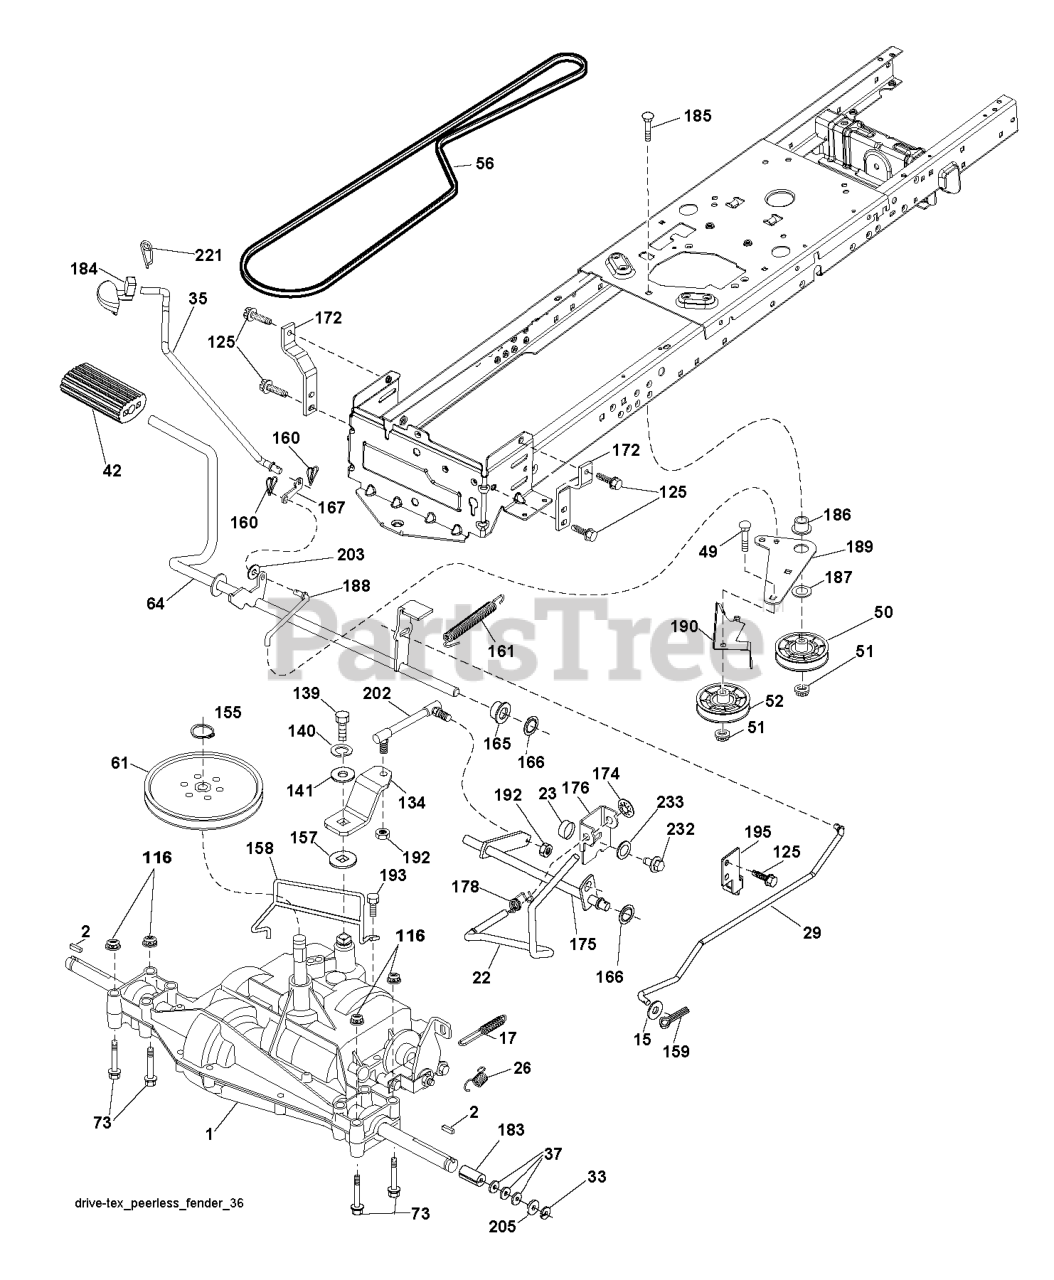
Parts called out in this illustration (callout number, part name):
2	SQUARE KEY
15	WASHER
17	SPRING.BRAKE.PEERLESS.TEX
22	ROD.SHIFT.FENDER.TLT.2006
23	KNOB.DUCKHEAD.1/2
26	SPRING.BRAKE.RTN.GR.DR
29	ROD.BRAKE.PEERLESS
35	ROD.CNTRL.PARK.PREDATOR.LT.TEX
42	PEDAL COVER T
50	IDLER.FLAT.910.OFFSET
51	NUT LOCK FLG 3/8-16 UNC
52	IDLER.V-GROOVE.910.OFFSET
56	V-BELT.TRACTOR.DRIVE.P
61	PULLEY TRANS
64	SHAFT.ASM.PEDAL.BRAKE.
73	BOLT HEX 5/16-18 GR 5
116	NUT LOCK HEX FLANGE 5/16-18
125	SCREW
139	BOLT 1/4-28X3/4
140	LOCKWASHER
141	WASHER LT
155	RETAINING RING LT
157	WASH-SHFT PLT LT
158	KEEPER.PMS.18/20.D4365
159	COTTER PIN
160	RETAINER CLIP
161	SPRING, RETURN LT
165	BUSHING.SHAFT.BRAKE.HAND
166	NUT.PUSH.625
167	LATCH.BRAKE.SPRING
172	STRAP.TRQ.LH.GEAR.DRIV
174	NUT.PUSH.500.2006
175	SHAFT ASM SHIFT
176	ARM.CLEVIS.ROD.SHIFT
178	SPRING.SHIFT.GT2006
183	SPACER AXLE
184	HANDLE PARKING BRAKE
186	SPACER.RETAINER
187	WASHER 12/32X2X10GA
188	RP.LINK.CLUTCH.GROUND.DRIVE
189	BELLCRANK.GROUND.DRIVE.TEX.
190	KEEPER.BELLCRANK.DRIVE
192	NUT LOCK CENTER 1/4 -28 FNTHD
193	SCREW 5/16"
195	BRKT.ROD.BRAKE.PEERLES
202	LINK.SHIFT.PMST.18" (SPG1286)
203	WASHER
221	RETAINER.SPRING.CLIP.H
232	BOLT FIN HEX 7/16-14 X 1
233	WASHER SERRATED
